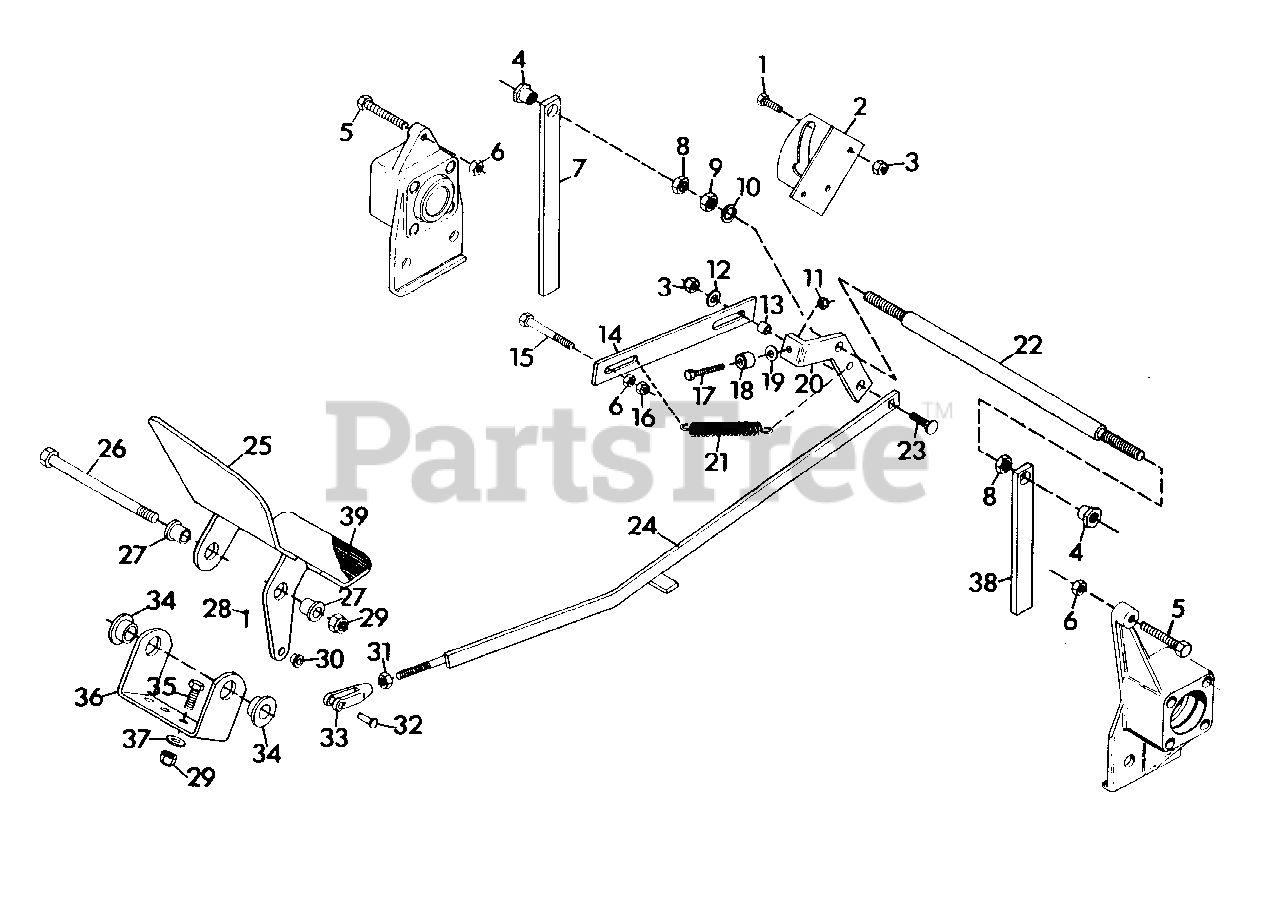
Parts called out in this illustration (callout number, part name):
1	BOLT, HEX 5/16-18X1.00
2	WELDMENT, FWD-REV ACTUATING
3	NUT, LOCK 5/16-18
4	BUSHING, FWD-REV SLIDE ROD
5	BOLT, HEX 3/8-16X2.50
6	NUT, HEX 3/8-16
7	SPRING, REVERSE CLUTCH
8	NUT, JAM 1/2-13 HEX
9	NUT, HEX 1/2-13
10	WASHER, LOCK 1/2 SP HEAVY
11	NUT, LOCK 1/4-28
12	WASHER, FLAT .313X.875X.065
13	BUSHING, FWD-REV LINKAGE
14	STRAP, NEUTRAL DETENT
15	BOLT, HEX 3/8-16X3.00
16	NUT, LOCK 3/8-16
17	BOLT, HEX 1/4-28X1.38 GR. 8
18	ROLLER, CLUTCH CAM
19	WASHER, FLAT .281X.625X.065
20	ARM, FWD-REV CLUTCH ROLL
21	SPRING, NEUTRAL DETENT
22	ROD, FWD-REV SLIDE
23	BOLT, 5/16-18X1.25 RD HD SQ NK
24	WELDMENT, FWD-REV SHIFTER
25	PEDAL, FOOT CLUTCH
26	BOLT, HEX 1/2-13X6.50
27	BUSHING, .513X.750X.625
28	PIN, COTTER .09X.75
29	NUT, LOCK 1/2-13
30	BUSHING, NYLON .32X.437X.248
31	NUT, HEX 5/16-24
32	PIN, CLEVIS 5/16X.812
33	YOKE
34	BUSHING, NYLON .76X1.00X.76 FLG
35	BOLT, HEX 1/2-13X1.25
36	BRACKET, CLUTCH PEDAL PIVOT
37	WASHER, FLAT .531X1.250X.100
38	SPRING, FWD-REV CLUTCH
39	PAD
